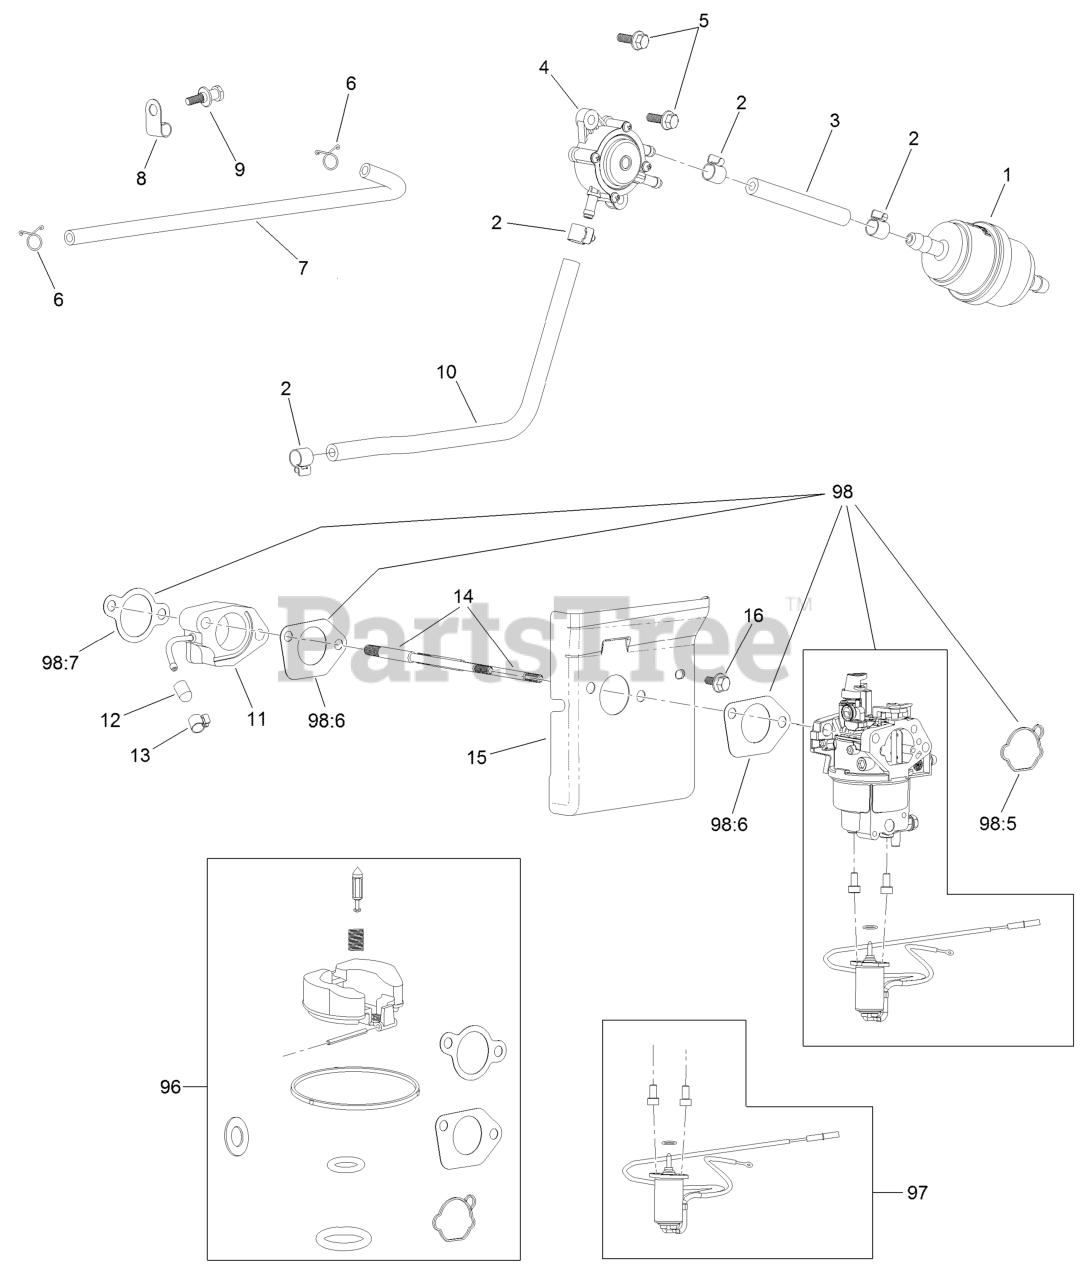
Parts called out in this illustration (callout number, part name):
1	FILTER-FUEL
2	CLAMP-FUEL LINE
3	LINE-FUEL
4	PUMP-PULSE, FUEL
5	SCREW-HHF
6	CLAMP-HOSE
7	LINE-PULSE
8	CLAMP-J
9	SCREW-SHOULDER, HH
10	LINE-FUEL
11	INSULATOR-CARBURETOR
12	CAP-SEAL
13	CLAMP-HOSE
14	STUD-MOUNT, CARBURETOR
16	SCREW-HHF
96	CARB REPAIR KIT WITH GASK
97	SOLENOID KIT
98:5	GASKET-CARBURETOR
98:6	GASKET-CARBURETOR
98:7	GASKET-CARBURETOR
